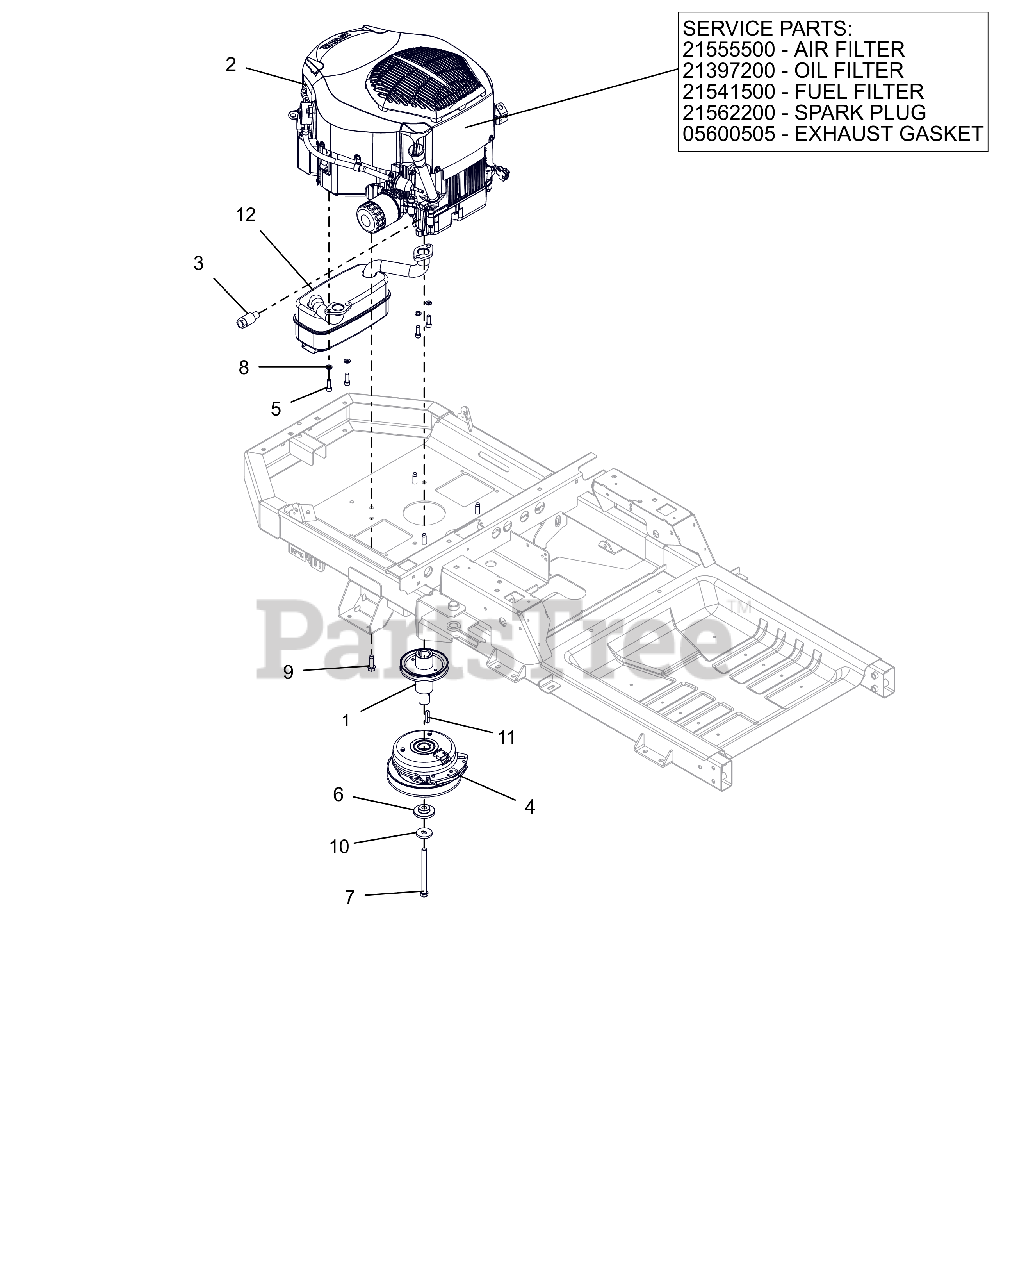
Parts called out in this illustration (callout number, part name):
1	WLDMT, DRIVE SHEAVE (LG XL)CZC
2	ENGINE, KOHLER TWIN - 25HP
2	AIR CLEANER, KOHLER
2	FILTER, OIL - KOH CV20
2	FILTER, FUEL
2	PLUG, SPARK (RFI)
2	GASKET, MUFFLER COURAGE TWIN
3	DRAIN, OIL
4	CLUTCH,105FTLB MONOPOLE 6.83"
5	SCR-CAP .31-18X.88 S/HD G8 ZCC
6	BSHG-FLG .469X1.06X.574X2.0
7	BLT-HEX.438-20X5 GR8 YZ NYTORQ
8	WSHR,LK-REG .312X.078 ZCC
9	SCR,TAP .375-16X1.25HWH TR ZCC
10	WASHER, 7/16" SPRING DISK
11	KEY-SQ .25 X 1.25 X .25 SAE
12	MUFFLER - KOHLER
